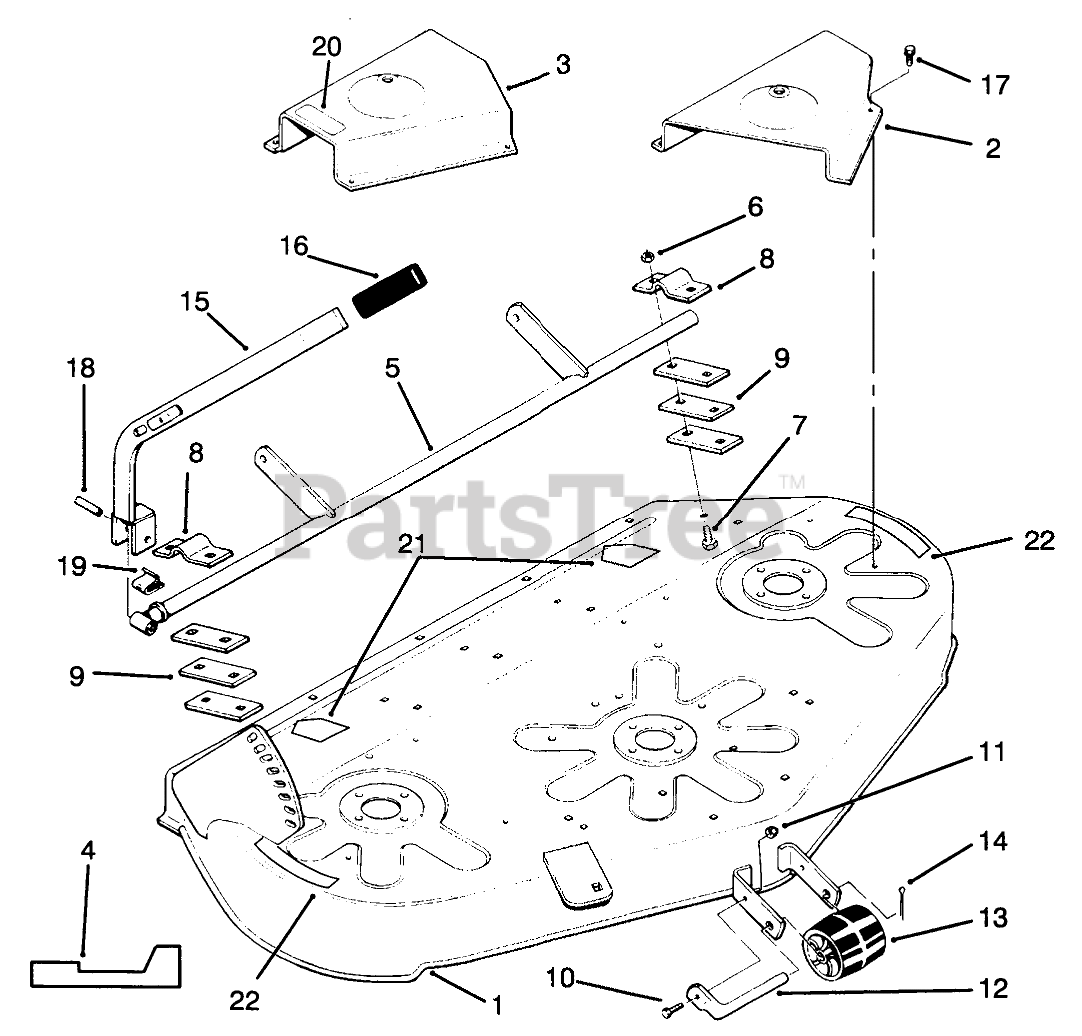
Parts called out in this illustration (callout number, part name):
1	Deck Assembly (Incl. Safety Decals)
2	Belt Cover LH
3	Belt Cover RH
4	DECAL-42" RECYCLER
5	Lift Support
6	NUT-LOCK, NI
7	SCREW-CARR
9	Bar
10	SCREW-HH
11	NUT-LOCK, NI
12	ROLLER-SHAFT
13	Roller
14	PIN-COTTER
15	Lever
17	SCREW-HWH
18	SPIROL PIN 3/8X1 1/2
19	CLIP-SPRING
20	DECAL-HOC
21	DECAL-DANGER
22	DECAL - DANGER
